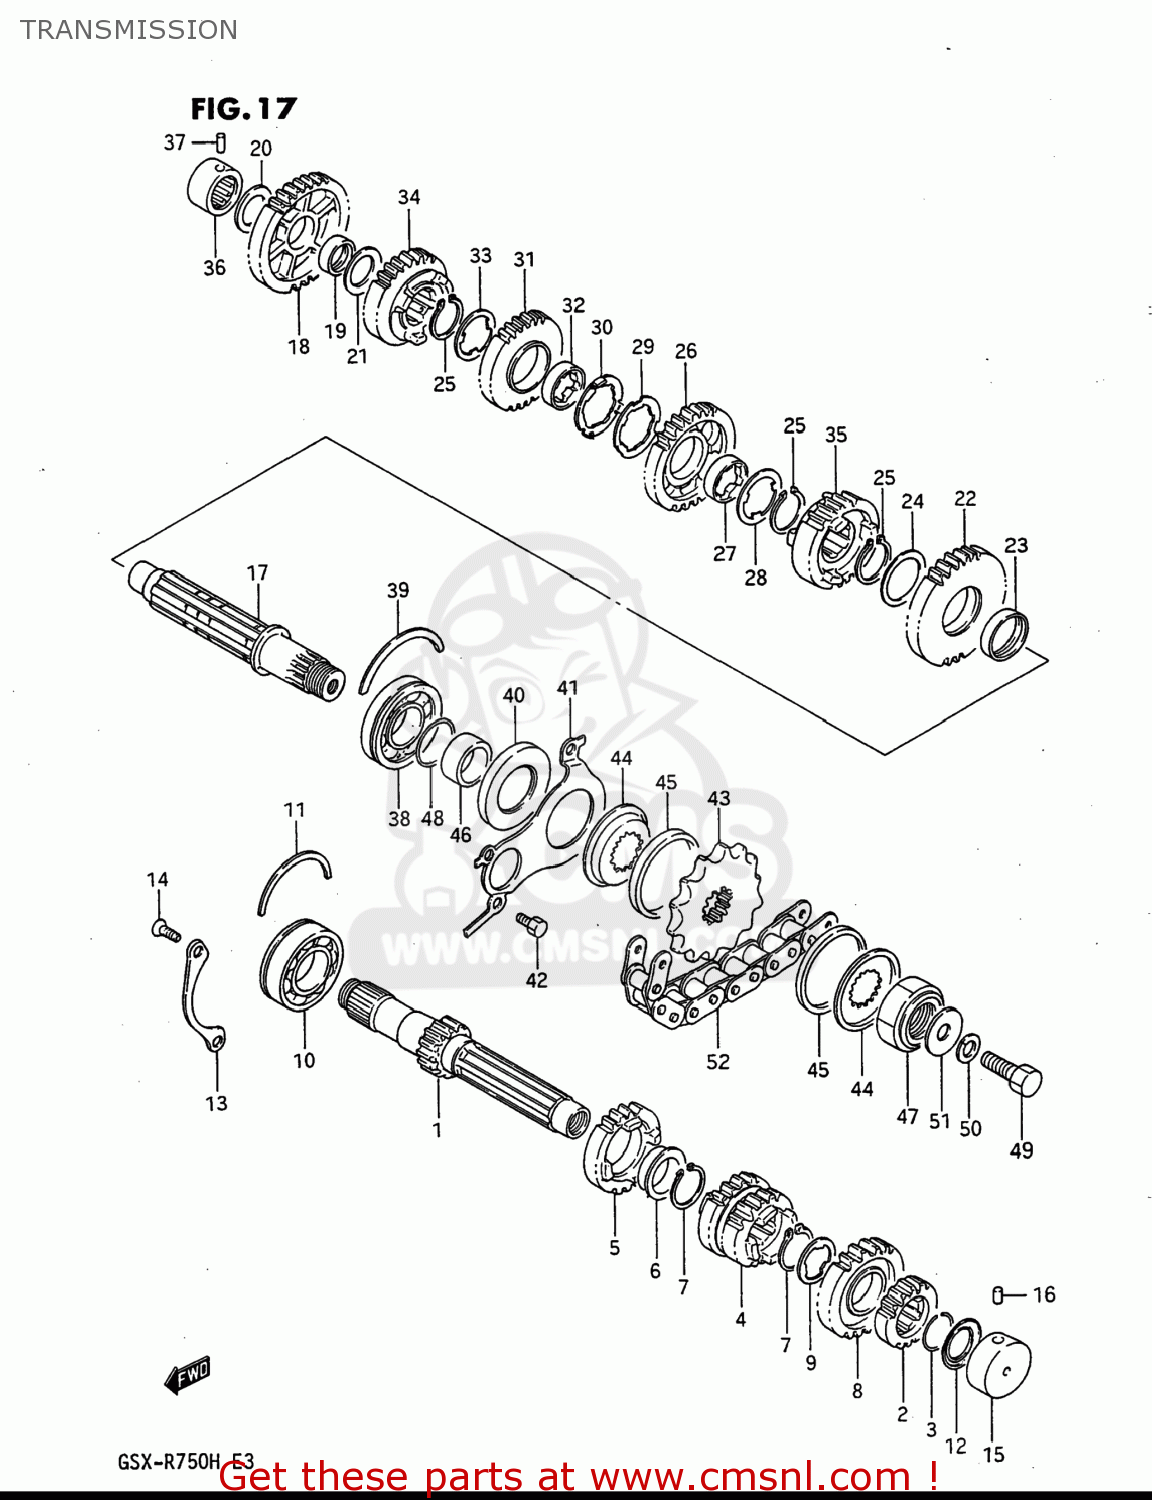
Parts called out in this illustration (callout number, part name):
1	SHAFT,COUNTER
2	GEAR,2ND DRIVE(NT:16)
3	RING,SNAP
4	GEAR,3RD & 4TH DRIVE(NT:17/20)
5	GEAR,5TH DRIVE(NT:22)
6	BUSHING
7	RING,SNAP
8	GEAR,SIXTH DRIVE
9	WASHER,LOCK
10	BEARING(25X62X17)
11	C-RING
12	SEAL,OIL(20X31.2X2.7)
13	RETAINER,CNTR SHAFT BEARING
14	SCREW
15	BEARING(20X34X17.5)
16	PIN
17	SHAFT,DRIVE
18	GEAR,1ST DRIVEN(NT:36)
19	BUSH(22X26X9)
20	WASHER
21	WASHER
22	GEAR,SECOND DRIVEN
23	BUSH(28X32X8)
24	WASHER, THRUST
25	CIRCLIP
26	GEAR,3RD DRIVEN(NT:28)
27	BUSH
28	WASHER,LOCK
29	WASHER,LOCK
30	WASHER
31	GEAR,FOURTH DRIVEN
32	BUSH
33	WASHER,LOCK
34	GEAR,5TH DRIVEN(NT:27)
35	GEAR,SIXTH DRIVEN
36	BEARING(20X34X20)
37	PIN
38	BALL BEARING 25X62X17
39	C-RING
40	SEAL,OIL(34X62X6)
41	RETAINER,DRIVESHAFT O
42	BOLT
43	SPROCKET,ENGINE
44	HOLDER,SPROCKET DAMPER
45	DAMPER,SPROCKET
46	SPACER (25X34X16.1)
47	NUT
48	O RING(D:1,ID:24.5)
49	BOLT
50	WASHER,LOCK
51	WASHER
52	CHAIN ASSEMBLY,DRIVE
